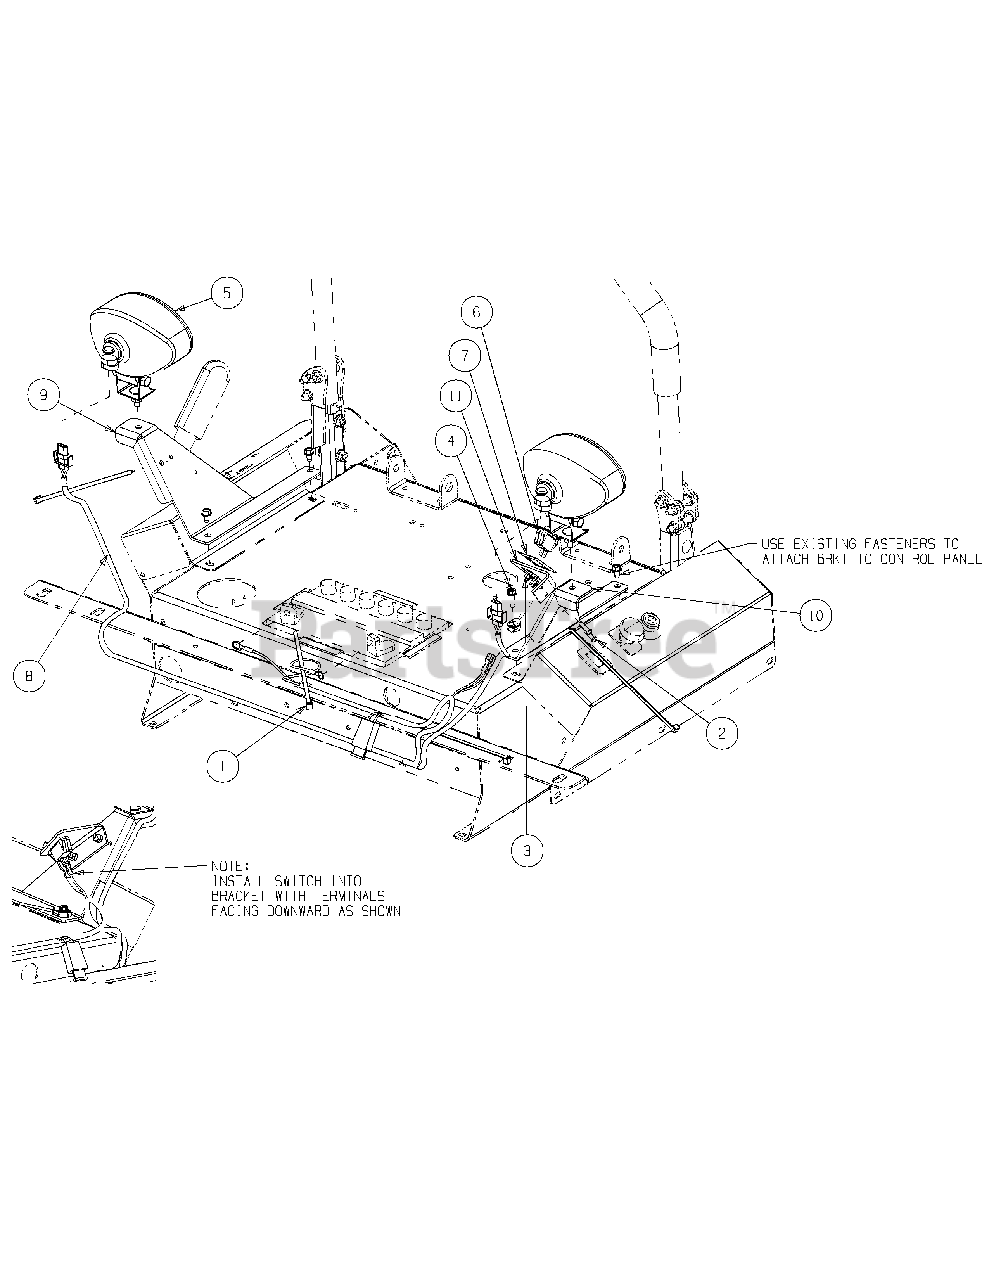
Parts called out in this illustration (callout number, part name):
1	Cable Tie
2	Phillips Head Machine Screw, 10-32 x 5/8
3	Nut, #10-32, Nylon Lock
4	Self Tapping Screw, 1/4-20 x .75
5	Oval Work Lamp
6	Switch
7	Label, Headlamp, On/Off
8	Harness Assembly
